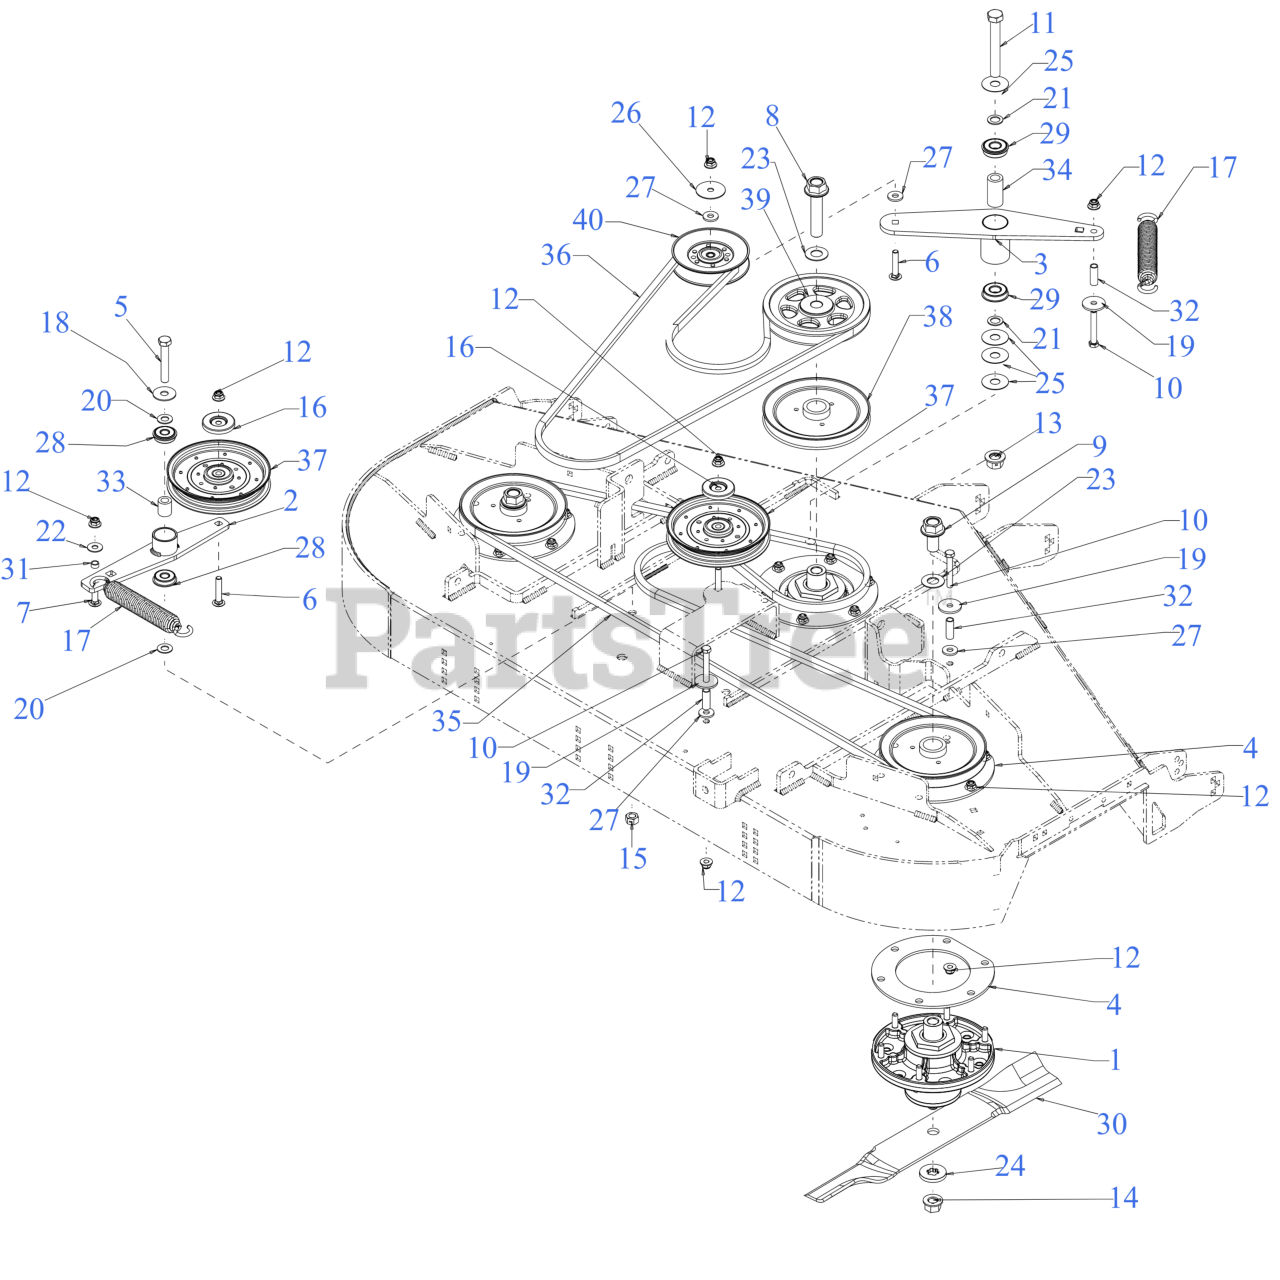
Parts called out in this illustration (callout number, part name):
1	SPINDLE ASSEMBLY
2	IDLER BRACKET
3	IDLER BRACKET
4	SPINDLE SUPPORT BRACKET TOP/BTM
5	SCREW-HEX 1/2-13 x 3.00
6	CARRIAGE BOLT 3/8-16 x 2
7	CARRIAGE BOLT 3/8-16 X1.25 GR5
8	CAP SCREW-HHFLG 3/4-10 X 3.50 GR8
9	CAP SCREW-HHFLG 3/4-10 X 1.50 GR8
10	HEX SCREW-3/8-16X2.5 GR5
11	SCREW 5/8-18X4.5 GR5
14	FLANGE NUT - 5/8-18 GDE 8
15	HEX NUT CTR LK 1/2-13
16	PULLEY CAP
17	SPRING 1.25" DIA x 8.5" LONG
18	WASHER .51 x 1.5 x .07
19	FLAT WASHER .390x1.500x.134
20	FLAT WASHER .510 x .995
21	FLAT WASHER
22	WASHER-.395 x 1.0 x .62
23	FLAT WASHER
24	FLAT WASHER - SPECIAL
25	THRUST WASHER .635x1.750x0.055
26	HUB CAP WASHER .406 x 1.92 x .060
27	FLAT WASHER .406ID X1.0 OD
28	ROLLER BEARING .5X1.37X.44
29	BALL BEARING W/RET
30	21" BLADE (HI LIFT)
30	Cub Cadet 60" BLADE SET
30	Genuine Factory Parts 60" BLADE SET
30	LOW-LIFT 21"BLADE (60"DECK)
30	BLADE-HI LIFT 21.0
30	BLADE-21"MULCH 60"
30	21" XTREME BLADE
33	SPACER 0.51 x 0.88 x 1.00
34	SPACER 0.63 x 1.00 x 2.01
36	BELT B SEC x 94.25
37	IDLER PULLEY
38	SPINDLE PULLEY 7"
39	PULLEY-7.01 OD x .75 ID
40	IDLER PULLEY 5.06 OD
